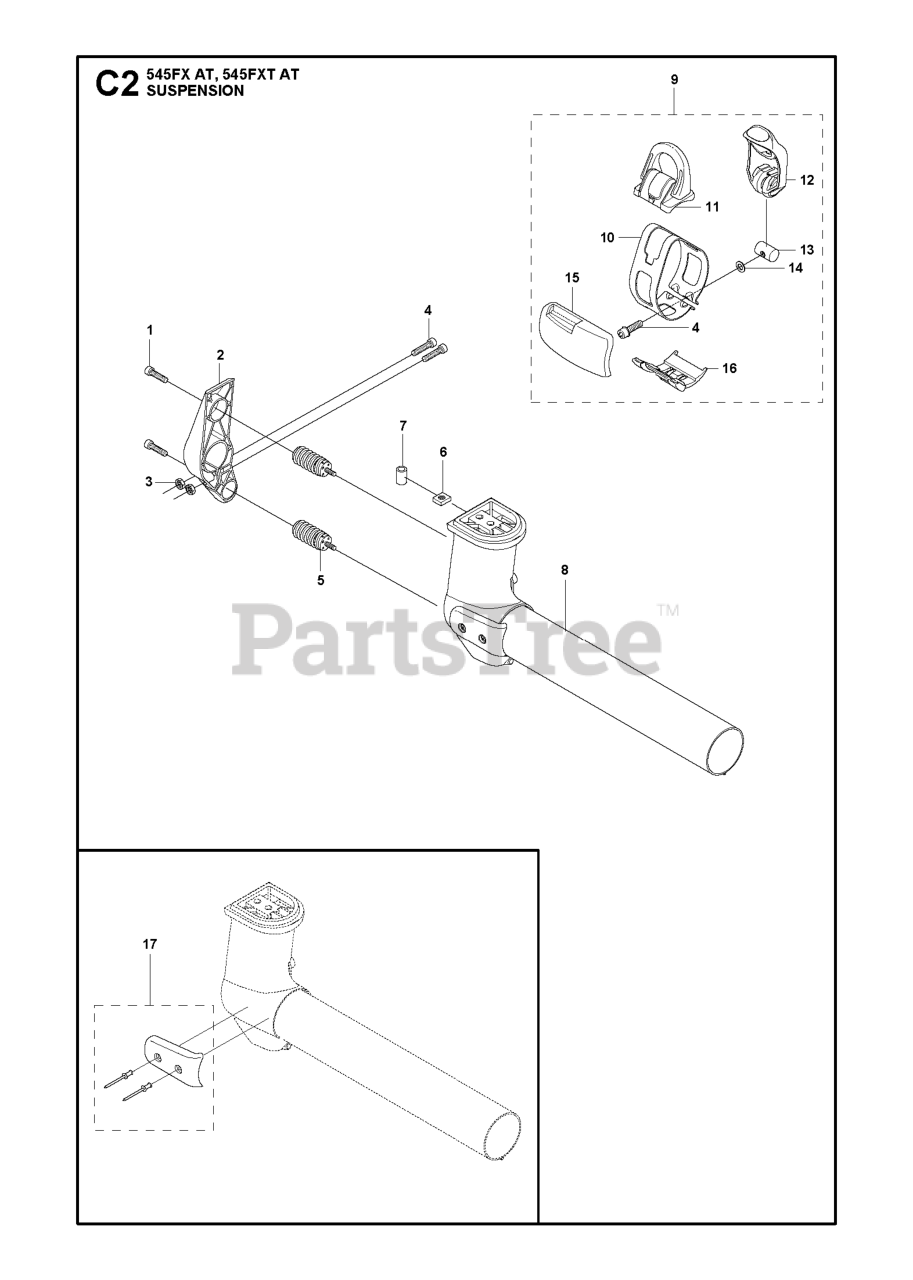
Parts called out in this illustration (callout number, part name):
2	HOLDER ANTIVIBRATION
5	ANTIVIBRATION ELEMENT ASSY
8	SUSPENSION
14	WASHER 5.3X12
15	WEAR PROTECTION
16	GUIDE RAIL
17	WEAR PROTECTION KIT
